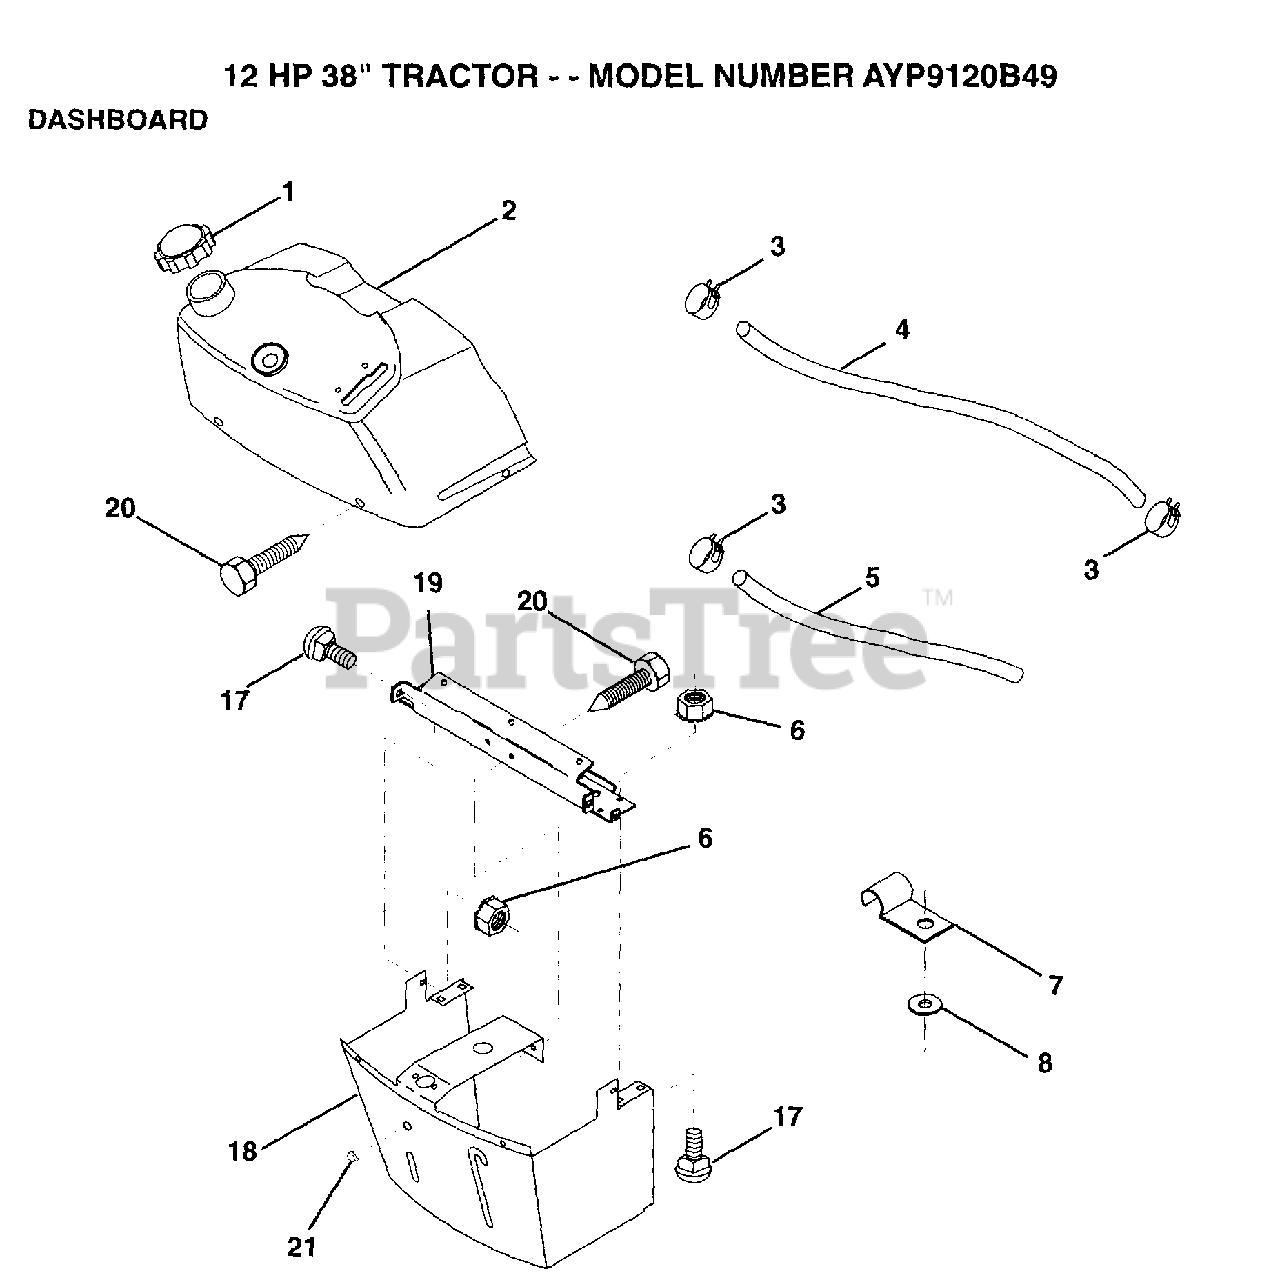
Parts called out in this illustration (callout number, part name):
1	CAP BLK FUEL LR
2	TANK.ASM.DASH.LR
3	HOSE CLAMP
5	FUEL LINE T
6	NUT
7	CLIP T
8	WASHER PM
17	BOLT
18	SUPT ASM DASH
19	CROSS BRACE
20	SCREW.1/4-20X1/2
21	PLUG DOME
